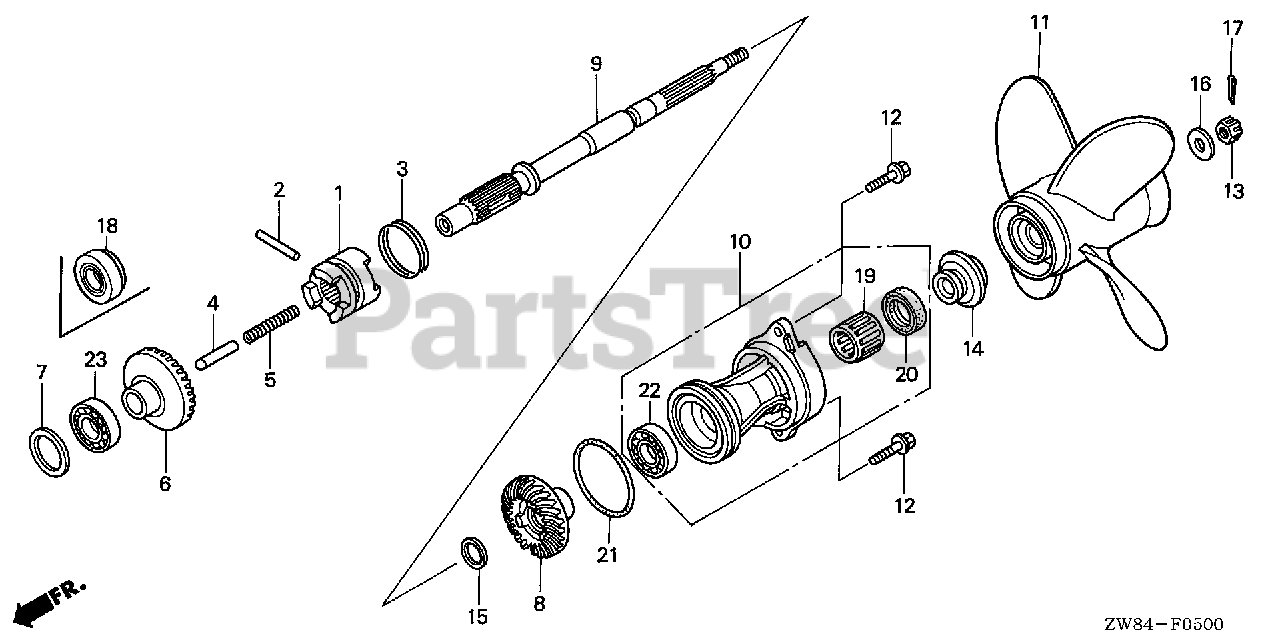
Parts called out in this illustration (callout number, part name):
1	SHIFTER, CLUTCH
2	PIN, SHIFTER (4X30)
3	RING, CROSS PIN
4	SLIDER, SHIFT
5	SPRING, SHIFT
6	GEAR, FR. BEVEL
7	SHIM A (40MM)
7	SHIM B (40MM)
7	SHIM C (40MM)
8	GEAR, RR. BEVEL
9	SHAFT, PROPELLER
10	HOLDER ASSY., PROPELLER SHAFT *NH282MU* (OYSTER SILVER METALLIC-U)
11	PROPELLER, FOUR BLADES (10X6-1/4)
11	PROPELLER, FOUR BLADES (10X6-1/2 HT)
11	PROPELLER, FOUR BLADES (9-1/4X7) *NH283*
11	PROPELLER, FOUR BLADES (9-1/4X8) *NH283* (STIN GRAY)
11	PROPELLER, FOUR BLADES (9-1/4X9) *NH283* (STIN GRAY)
11	PROPELLER, FOUR BLADES (9-1/4X10) *NH283*
11	PROPELLER, FOUR BLADES (9-1/4X11) *NH283*
12	BOLT, FLANGE (6X20)
13	NUT, CASTLE (10MM)
14	WASHER, PROPELLER THRUST
15	WASHER (18MM)
16	WASHER (10MM)
17	PIN, COTTER (3MM)
19	BEARING, NEEDLE (17X24X20)
20	SEAL, WATER (17MM)
21	O-RING (59.4X3.1)
22	BEARING, RADIAL BALL (6005)
23	BEARING, RADIAL BALL (6005)
